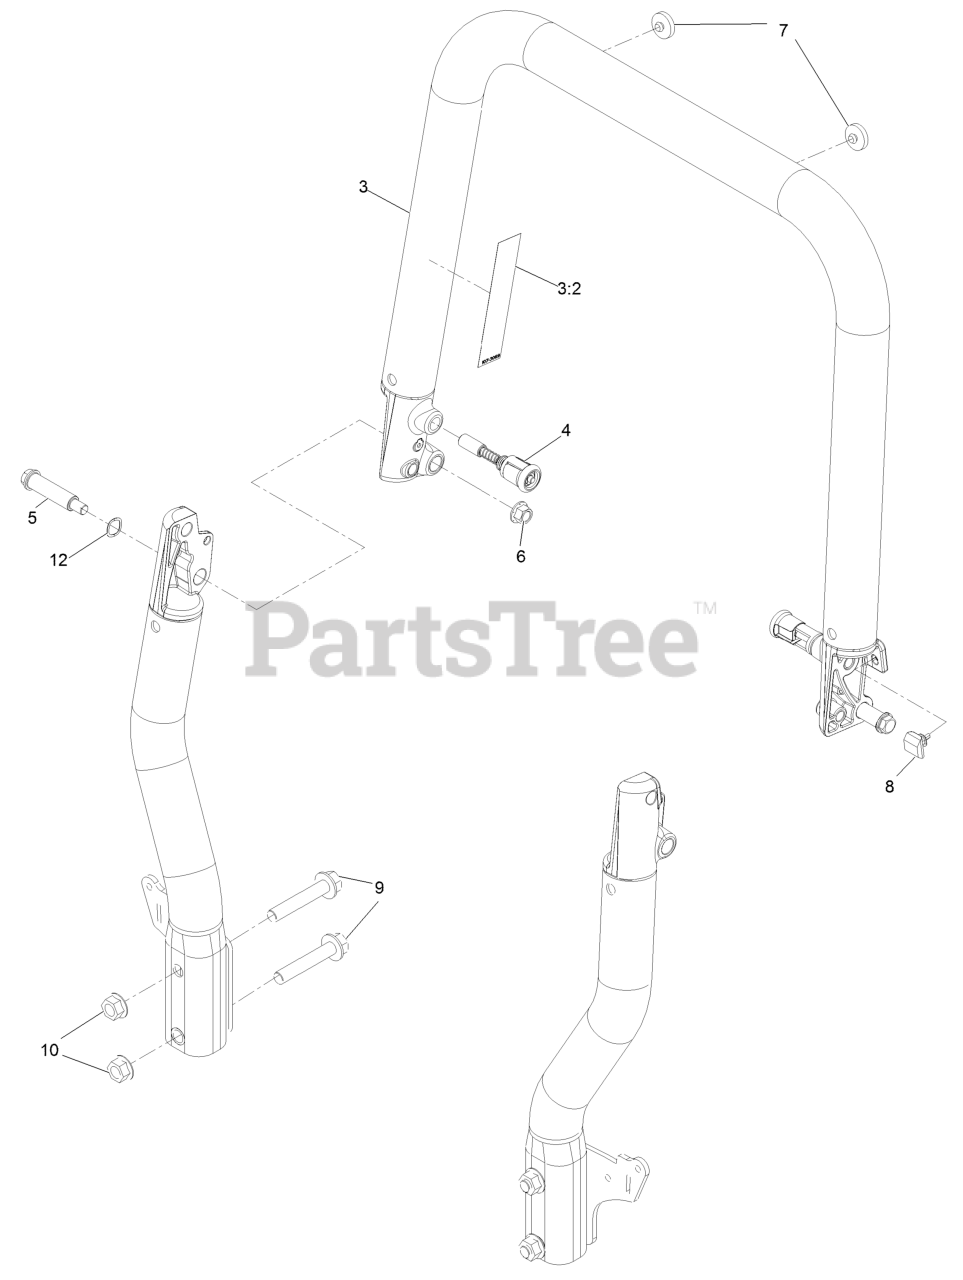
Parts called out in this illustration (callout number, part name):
3	Tube Top ASM
3:2	Decal-Warning, Folding ROPS
4	Pin-Spring
5	Bolt-Shoulder
6	Nut-Lock 1/2-13
7	Bumper-Push-In, Rubber
8	Bumper,ROPS
9	Screw-HHF 5/8-18 X 3 1/2 Gr 8
10	Nut-Whizlock 5/8-11
12	Washer-Wave
